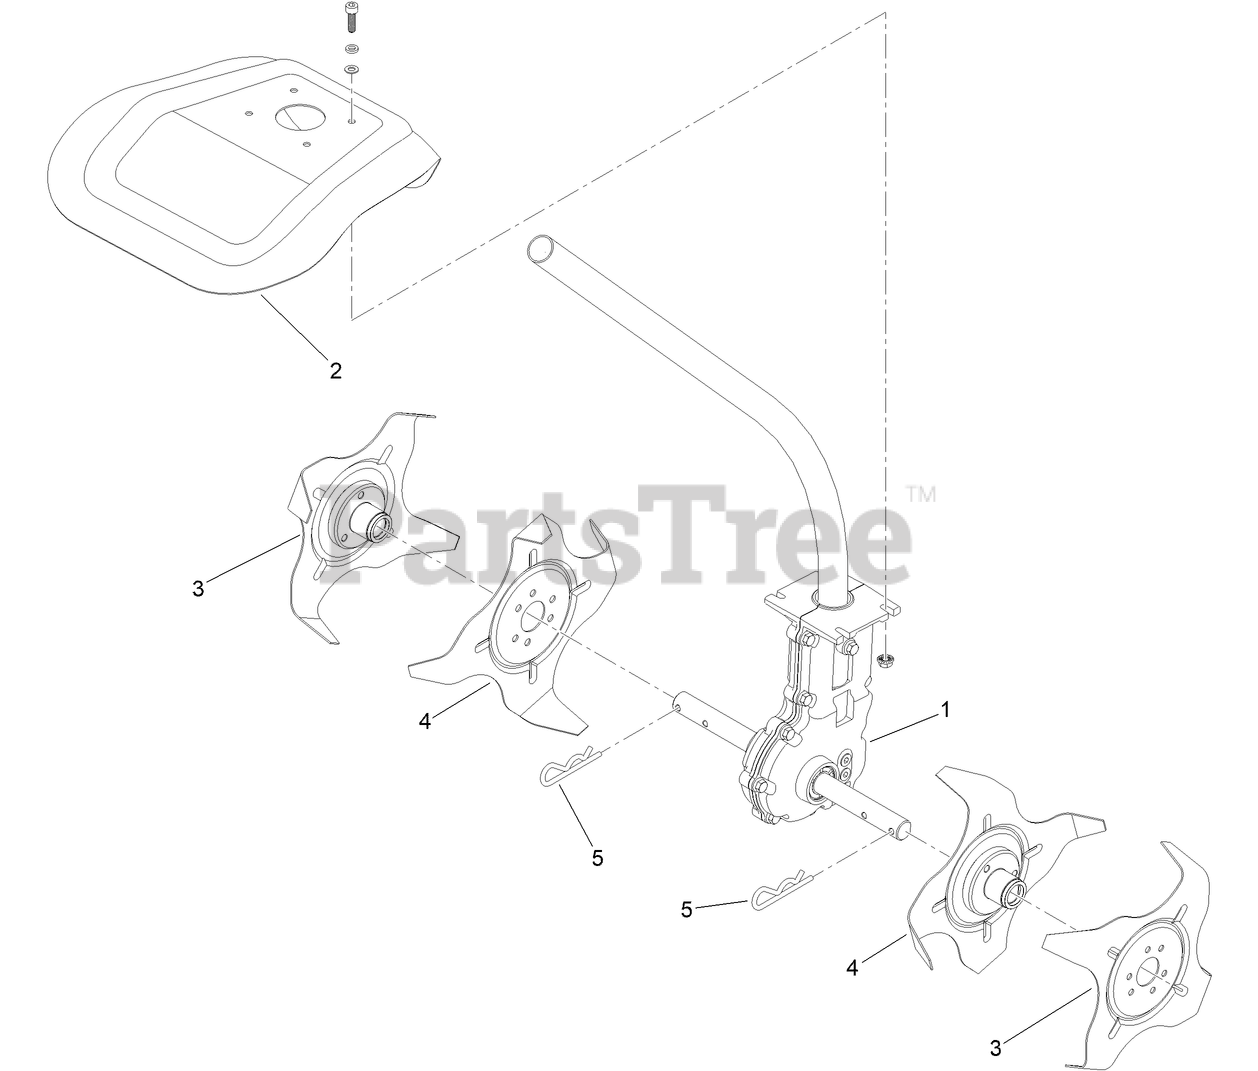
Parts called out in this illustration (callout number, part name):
1	GEAR BOX
2	AUGER COVER
3	BLADE SET (OUTER)
4	BLADE SET (INNER)
5	CLEVIS PIN SET (2)
